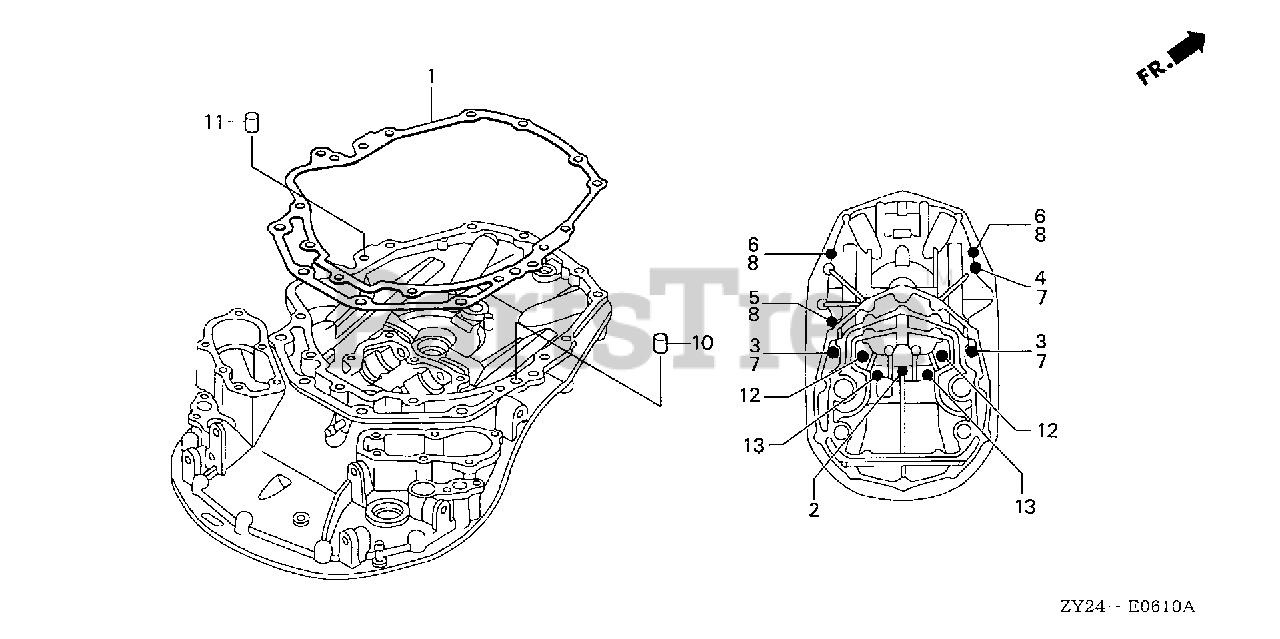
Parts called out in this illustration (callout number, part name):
1	GASKET, MOUNT CASE
2	BOLT, FLANGE (10X120) (SATO)
3	BOLT, HEX. (12X120)
4	BOLT, HEX. (12X65)
5	BOLT, HEX. (10X85)
6	BOLT, HEX. (10X60)
7	WASHER, PLAIN (12MM)
8	WASHER, PLAIN (10MM)
10	PIN, DOWEL (14X15)
11	PIN B, DOWEL (10X16)
12	BOLT, FLANGE (10X70)
13	BOLT, FLANGE (12X120)
